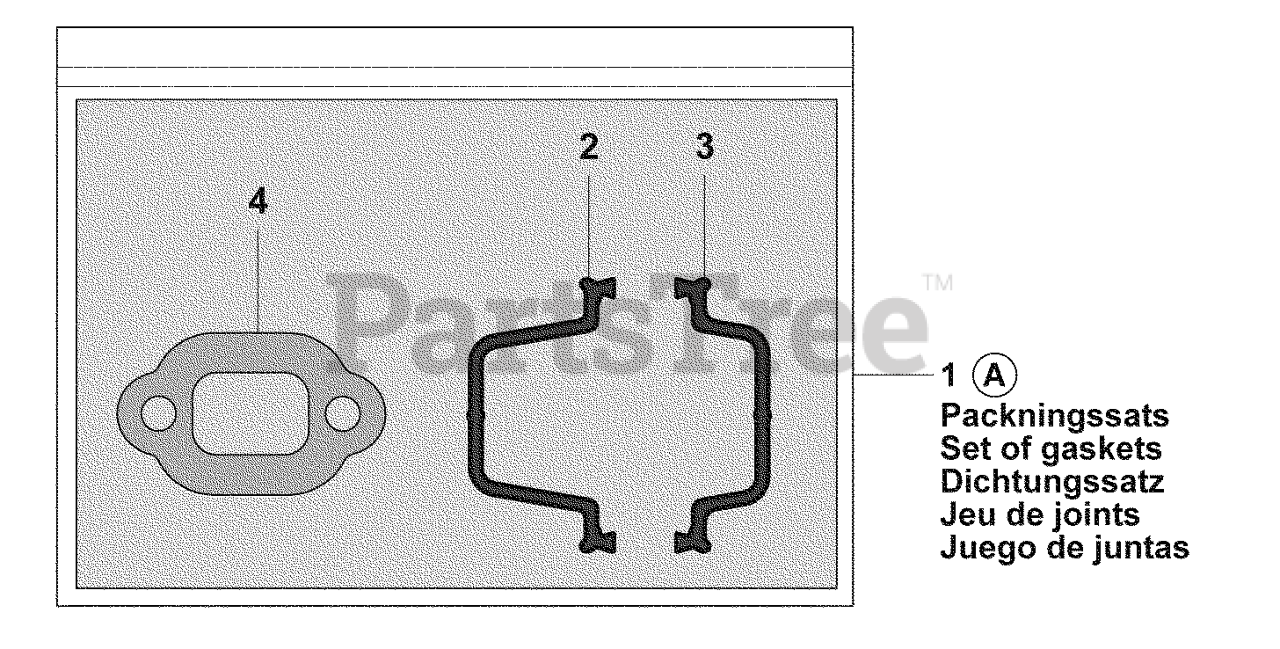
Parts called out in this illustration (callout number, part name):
1	GASKET SET
2	GASKET
3	GASKET
4	RP GASKET
